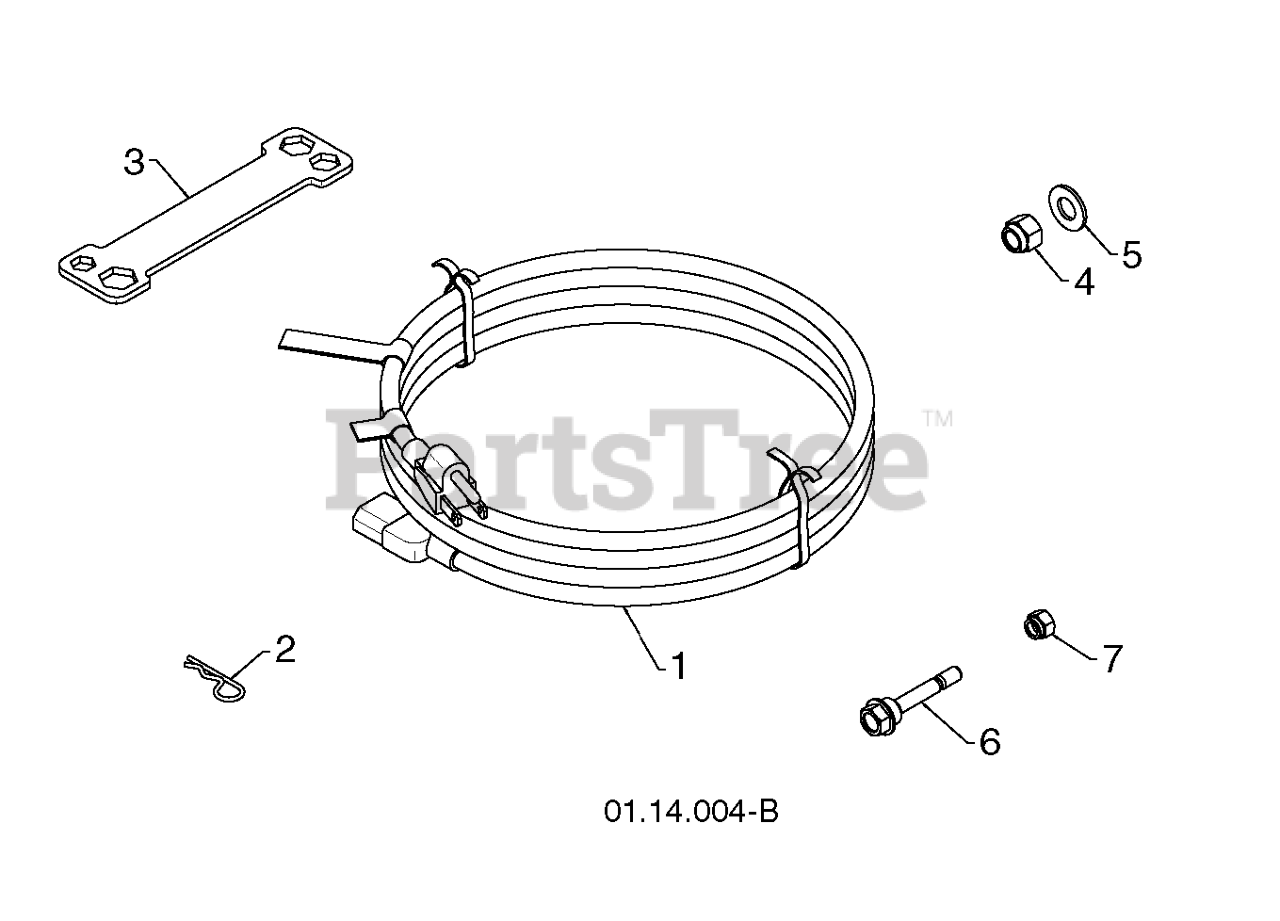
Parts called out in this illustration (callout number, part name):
1	CORD.ELECTRIC.10FT.120V.SNOW
2	SPRING RETAINER
3	WRENCH.SNOWTHROWER.ZINC.YZ
4	NUT
5	WASHER
6	BOLT.SHOULDER.SHEAR.1/4-20.
7	LOCKNUT.NYLOC.1/4-20
